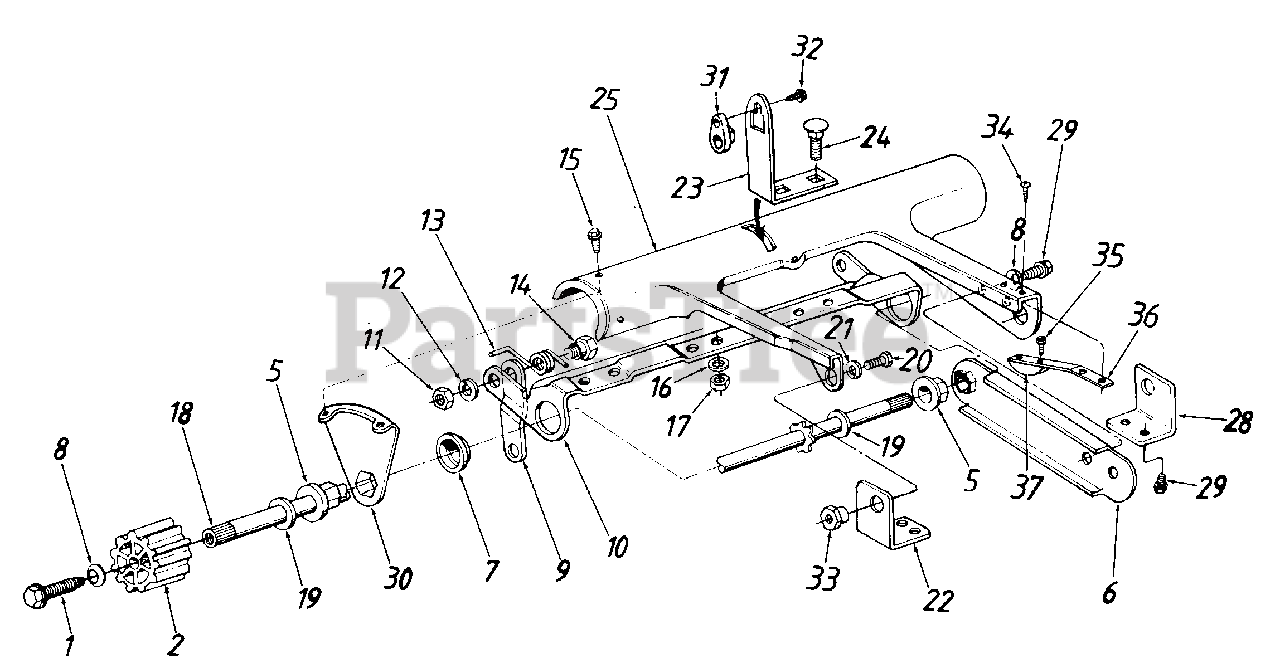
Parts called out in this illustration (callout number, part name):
1	Hex Wash. Hd. Tap Scr. 1/4-20 x .75" Lg.
2	Wheel Drive Pinion
5	Hex Flange Brg. .504" I.D.
8	Bell-Wash. .265" I.D. x .75" O.D.
11	Hex Nut 5/16-18 Thd.
12	L-Wash. 5/16" I.D.
13	Torsion Spring-R.H.
14	Shoulder Bolt .437" Dia.
15	Hex L-Hd. AB-Tap Scr. 1/4" x .62" Lg.
16	L-Wash. 1/4" I.D.
17	Hex Nut 1/4-20 Thd.
18	Drive Shaft Ass'y.
19	Fl-Wash. .531" I.D. x .93" O.D.
20	Hex Bolt 3/8-16 x .5" Lg.
21	L-Wash. 3/8" I.D.
32	Hex B-Tap Scr. #10 x .44"
33	Shld Nut .625" Dia. x .165" Lg.
34	Truss Mach. B-Tap Scr. #10 x .5" Lg.
35	Hex B-Tap Scr. #10 x 3/8" Lg.
36	Cantilever Spring
37	Chain Tensioner
